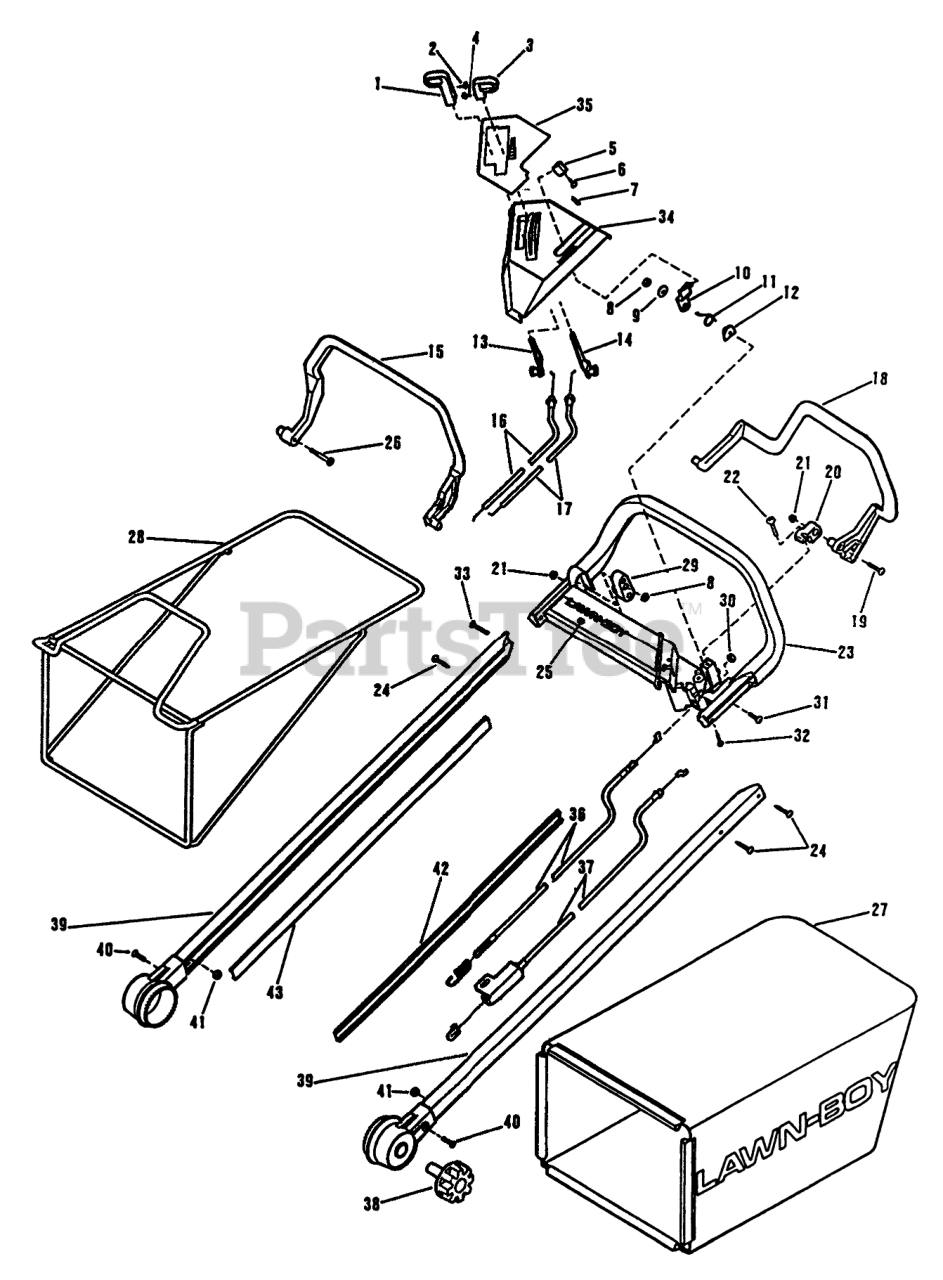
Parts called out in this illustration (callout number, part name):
1	KNOB & SCREW AY
2	SCREW-SELF TAP
3	KNOB & SCREW AY
4	SCREW-SELF TAP
5	KNOB & SCREW AY
6	SCREW-SELF TAP
7	PLUG - BUTTON
8	LOCKNUT E
9	WASHER
10	BBC LATCH LB
11	SPRING
12	SPACER
13	LEVER ASSM SPD SEL LB
14	LVR ASSM THROTTLE LB
15	Blade Brake Bail
16	CABLE AY. WESCON
17	CABLE
18	BAIL-S.P.
19	SCREW - TRUSS HEAD
20	PIVOT BAIL PL
21	LOCKNUT FLAN
22	SCREW - TRUSS HEAD
23	Handle and Decal Assembly
24	SCREW
25	DECAL - LAWNBOY
26	SCREW - TRUSS HEAD
27	REPL BAG FOR 684190
28	FRAME AY-GRASS BAGB
29	BLOCK BAIL PL
30	NUT - HEX JAM
31	SCREW-CROSS RECESS
32	SCREW - TRUSS HEAD
33	SCREW-TRUSS
34	UPPER CVR W/DECAL
35	PLATE-LOGO-INSTRUC
36	Cable Assy-Self-propelled
37	CABLE AY WESC
38	KNOB-HDLE MT.ASMB
39	Handle Shaft Assembly
40	SCREW
41	LOCKNUT FLAN
42	Handle Insert-Cable Side
43	INSERT - HANDLE
